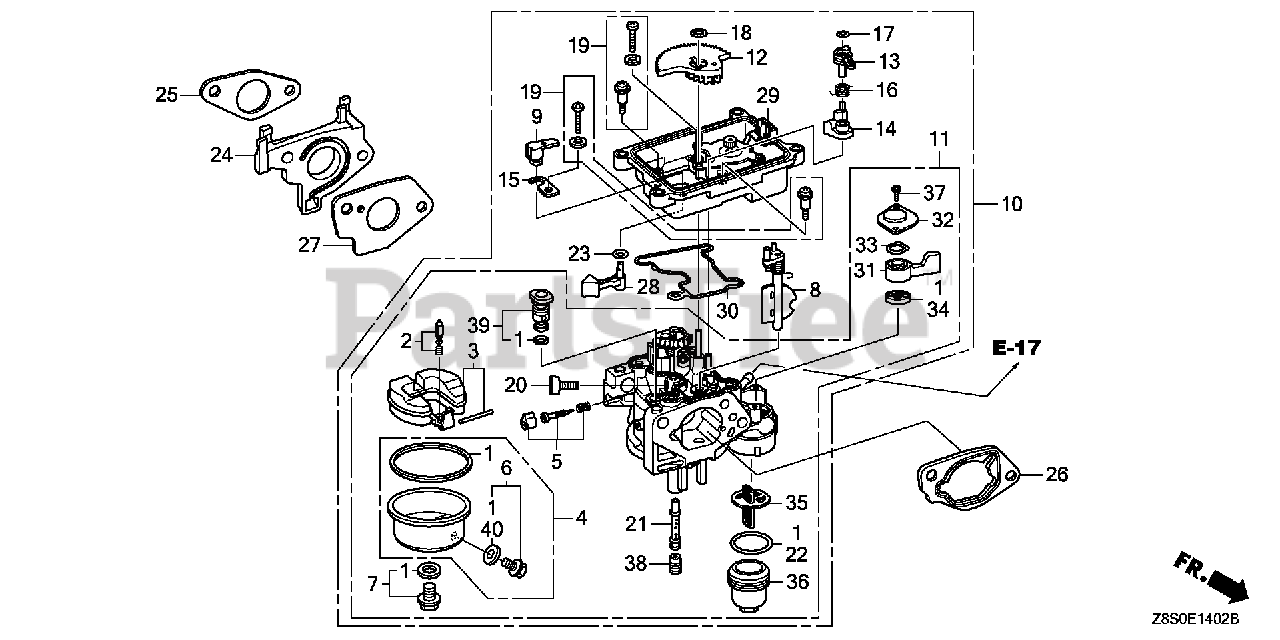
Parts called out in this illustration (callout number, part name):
1	GASKET SET (INCLUDES 16173-001-004)
2	VALVE SET, FLOAT
4	CHAMBER SET, FLOAT
6	SCREW SET, DRAIN
9	ARM, MANUAL START
10	CARBURETOR ASSY. (BE93B A) (NOT AVAILABLE)
11	CARBURETOR SET
12	GEAR, MIDDLE
13	ARM, CHOKE
14	LEVER, CHOKE CONTROL
16	SPRING, TORSION COIL
17	CLIP, SPECIAL
18	CLIP, SPECIAL
20	SCREW, STOP
21	NOZZLE, MAIN
22	GASKET, FUEL STRAINER CUP
23	O-RING (4.8X1.9)
24	INSULATOR, CARBURETOR
25	GASKET, INSULATOR
26	SPACER, CARBURETOR
27	GASKET, CARBURETOR
28	LEVER, MANUAL START
29	CASE, MOTOR
31	LEVER, PETCOCK
32	PLATE, LEVER SETTING
33	SPRING, PETCOCK LEVER
34	GASKET, PETCOCK
35	FILTER, CUP
36	CUP, FUEL STRAINER
37	SCREW, PAN (3X6)
38	JET, MAIN (#78)
38	JET, MAIN (#80)
38	JET, MAIN (#82)
39	JET SET, PILOT (#38)
40	WASHER, PLAIN (6.2X10.7 DRAIN)
